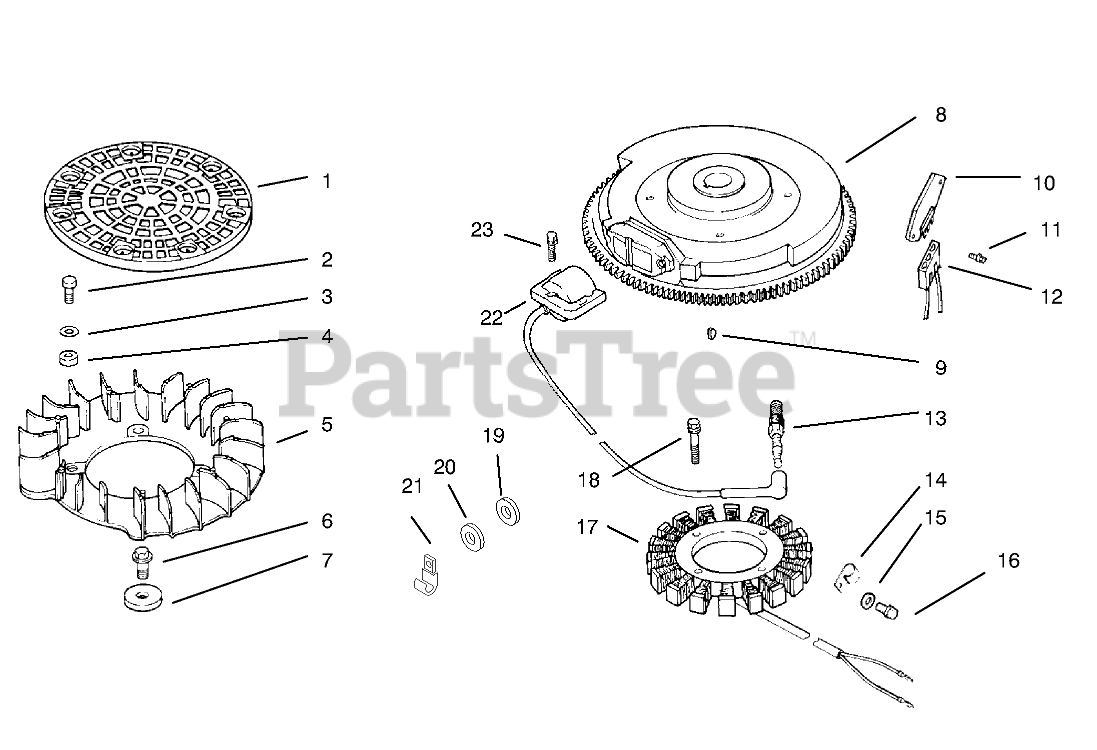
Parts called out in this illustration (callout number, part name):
1	Screen-Grass
2	Screw-Hex.
3	Washer
4	Spacer-Fan
5	Fan
6	Screw
7	Spacer
8	Flywheel
9	Key
10	Rectifier-Regulator
11	Screw
12	Connector
13	Plug-Spark
14	Clip
15	Washer
16	Screw
17	Stator-15 Amp
18	Screw
19	Washer
20	Washer
21	Clip
22	Module-Ignition
